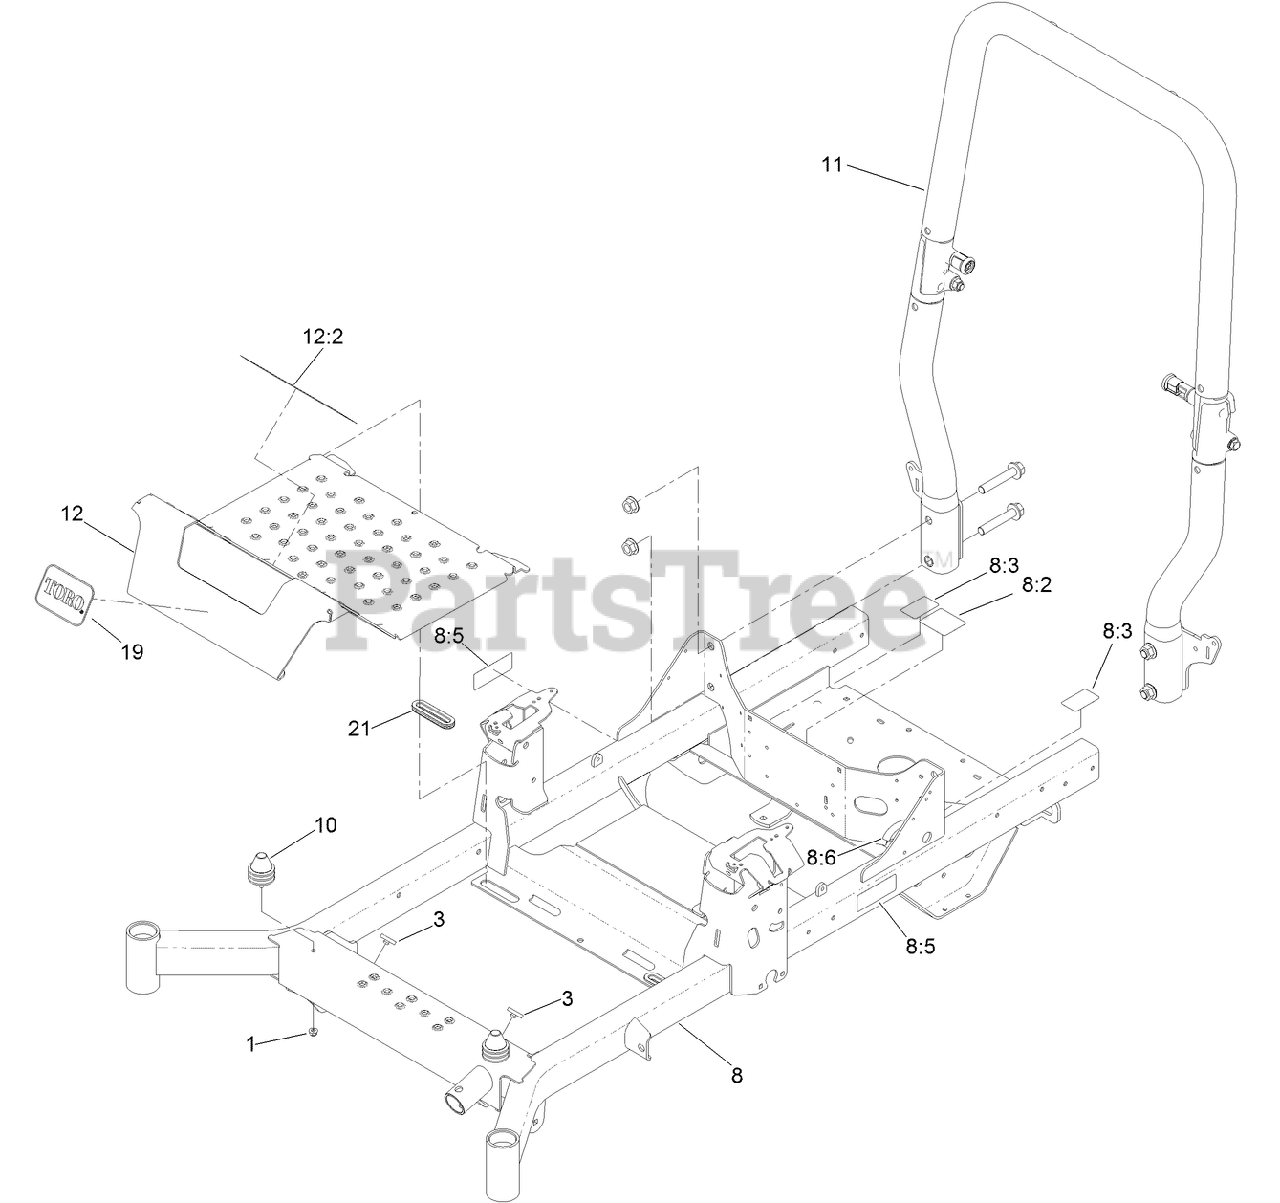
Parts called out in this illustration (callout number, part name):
1	NUT-HF, NI
3	BUMPER-PUSH-IN, RUBBER
8	FRAME ASM
8:2	DECAL-ROUTING, BELT
8:3	DECAL-RELEASE, DRIVE
8:5	DECAL-WARNING
8:6	STRIP-SEAL
10	ISOLATOR
11	ROPS ASM
12	PAN-FLOOR
12:2	DECAL-DANGER
19	DECAL
21	GROMMET-RUBBER
